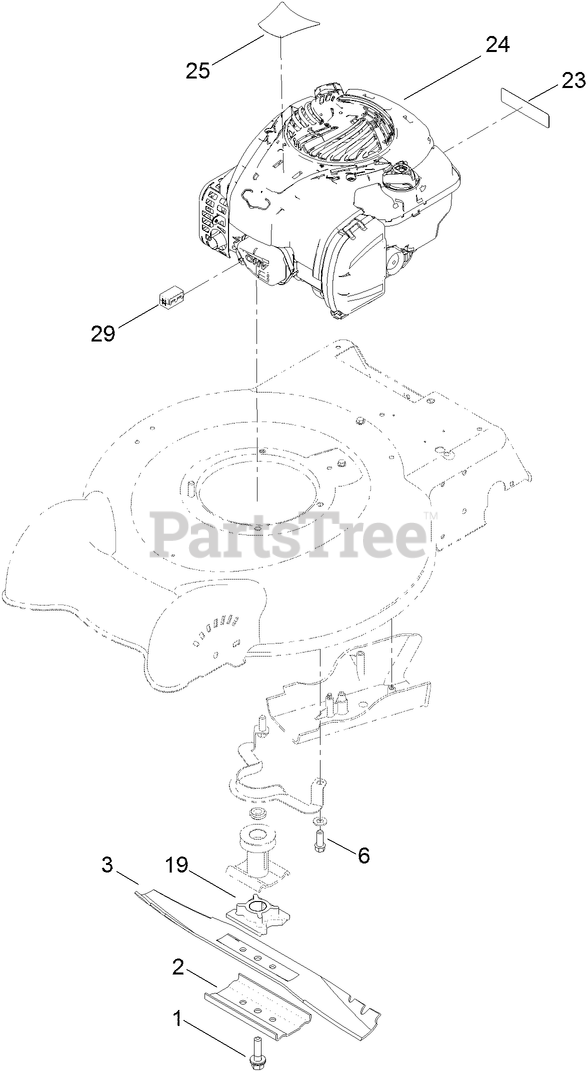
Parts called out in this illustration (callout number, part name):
1	BOLT-BLADE
2	SUPPORT-BLADE
6	SCREW-TAPTITE
19	RETAINER-BLADE
23	DECAL-ARRESTER, SPARK
25	DECAL-ENGINE
29	FERRITE-CLAMP
